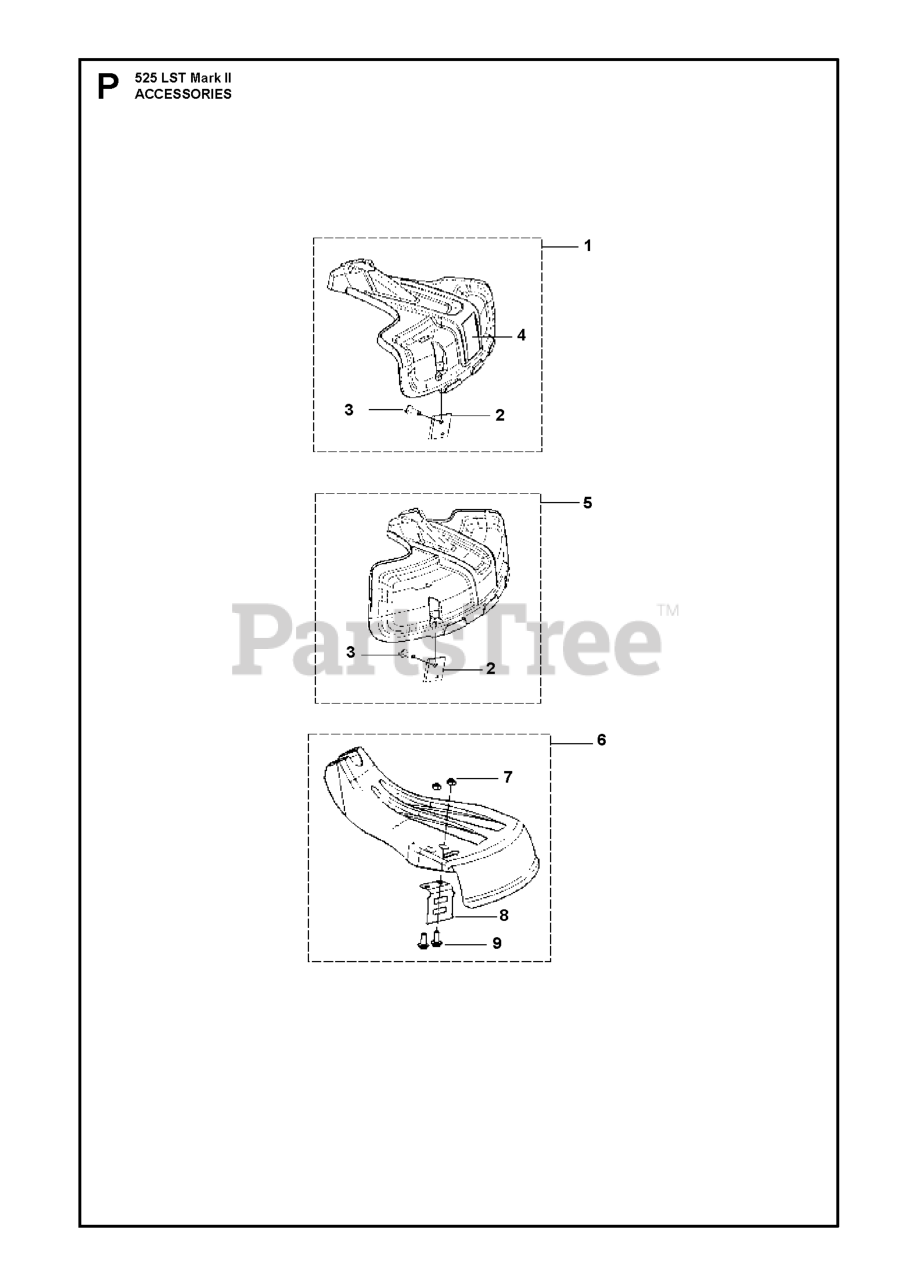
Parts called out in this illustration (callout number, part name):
1	TRIMMER GUARD 323L MFL.
2	LINE CUTTER
3	SCREW ITXSCFT PW4.8X16 T27 CH
5	COMBINATION GUARD
6	GUARD ASSY
